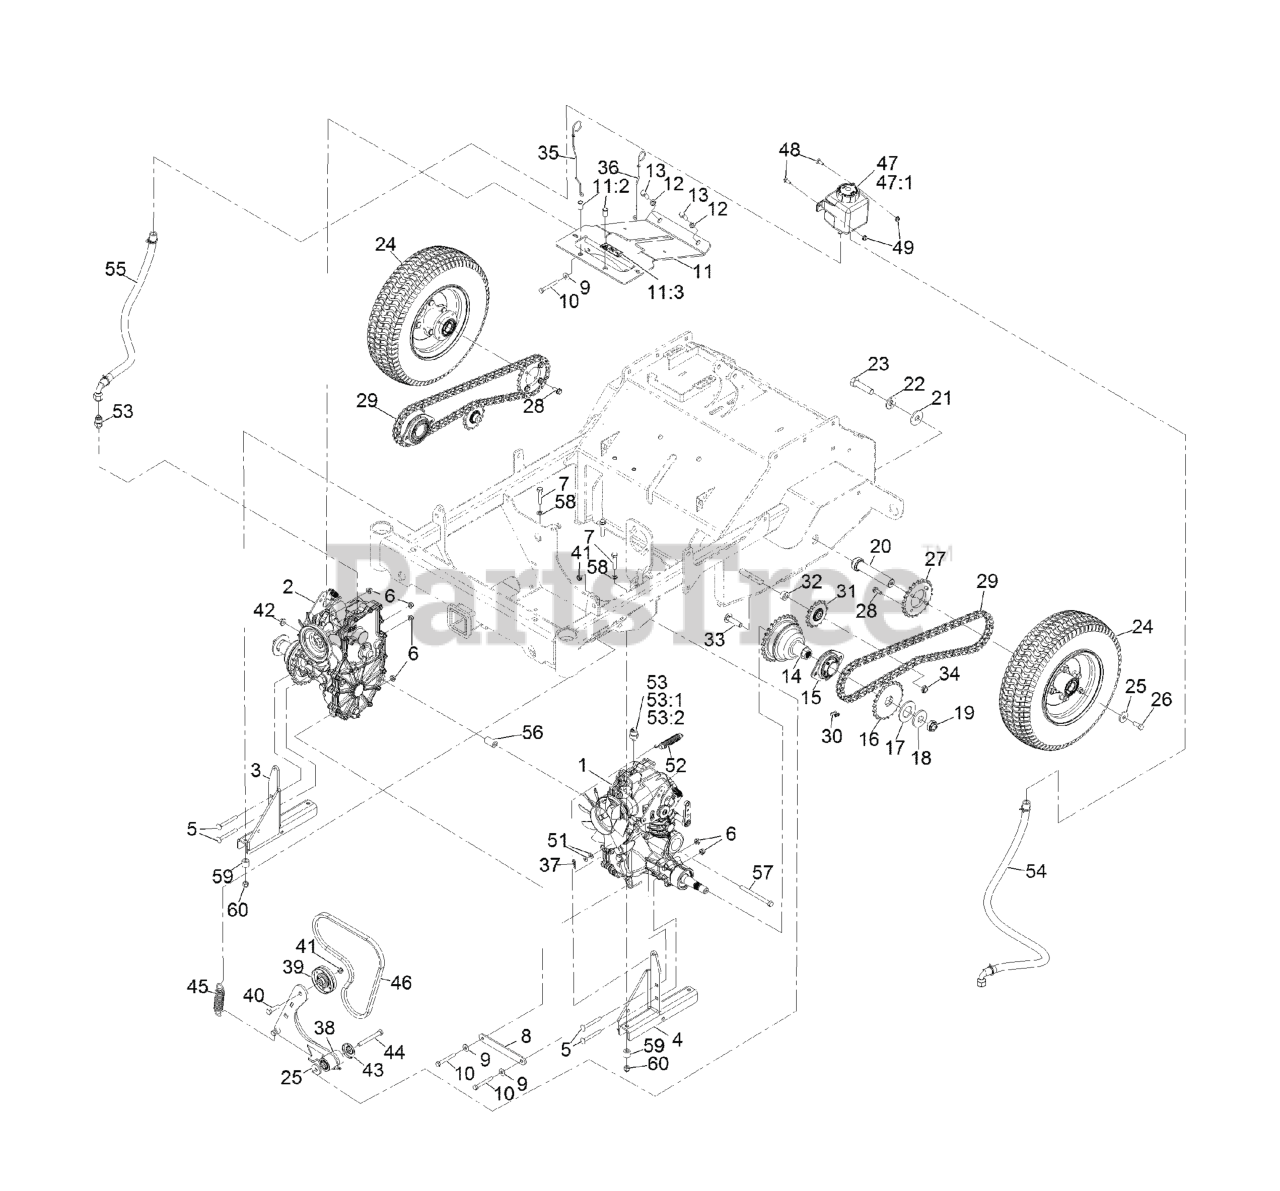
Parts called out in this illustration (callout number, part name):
1	HYDRO-ZT3100, LH
2	HYDRO-ZT3100, RH
3	MOUNT-HYDRO, RH
4	MOUNT-HYDRO, LH
5	SCREW-CARR
6	NUT-HF, NI
7	SCREW-HH
8	Crossmember-Transmission
9	WASHER-SPRING
10	SCREW-HH
11	SUPPORT-COVER
11:2	NUT-CLINCH
11:3	DECAL-DANGER
12	WASHER-LOCK
13	SCREW-HH
14	HUB-BELL
15	BEARING-FLANGED
16	SPROCKET
17	WASHER-SPACER
18	Washer-Belleville
19	NUT-LOCK
20	AXLE-WHEEL, DRIVE
21	WASHER-SPACER
22	Washer-Belleville
23	Screw-HH
24	WHEEL AND TIRE ASM
25	Washer-Flat
26	SCREW-HH, LOCK
27	SPROCKET
28	SCREW-HHF
29	CHAIN-ROLLER
30	LINK-CONNECTING
31	SPROCKET-IDLER, 15T
33	Screw-CARR
34	NUT-HEX
35	ROD-BYPASS, LH
36	ROD-BYPASS, RH
38	IDLER ARM ASM
39	PULLEY-IDLER
40	SCREW-HH
42	NUT-HF, NI
43	GUARD-TOP
44	SCREW-HH
45	SPRING-EXTENSION
46	BELT-V, COGGED
47	TANK-HYD
47:1	CAP-RESERVOIR, HYD
48	BOLT-CARR
52	SPRING-EXTENSION
53	FITTING-STRAIGHT
53:1	O-RING
54	HOSE ASM
55	HOSE ASM
57	SCREW-HH
58	SPACER-BRAKE, PARKING
60	NUT-LOCK
